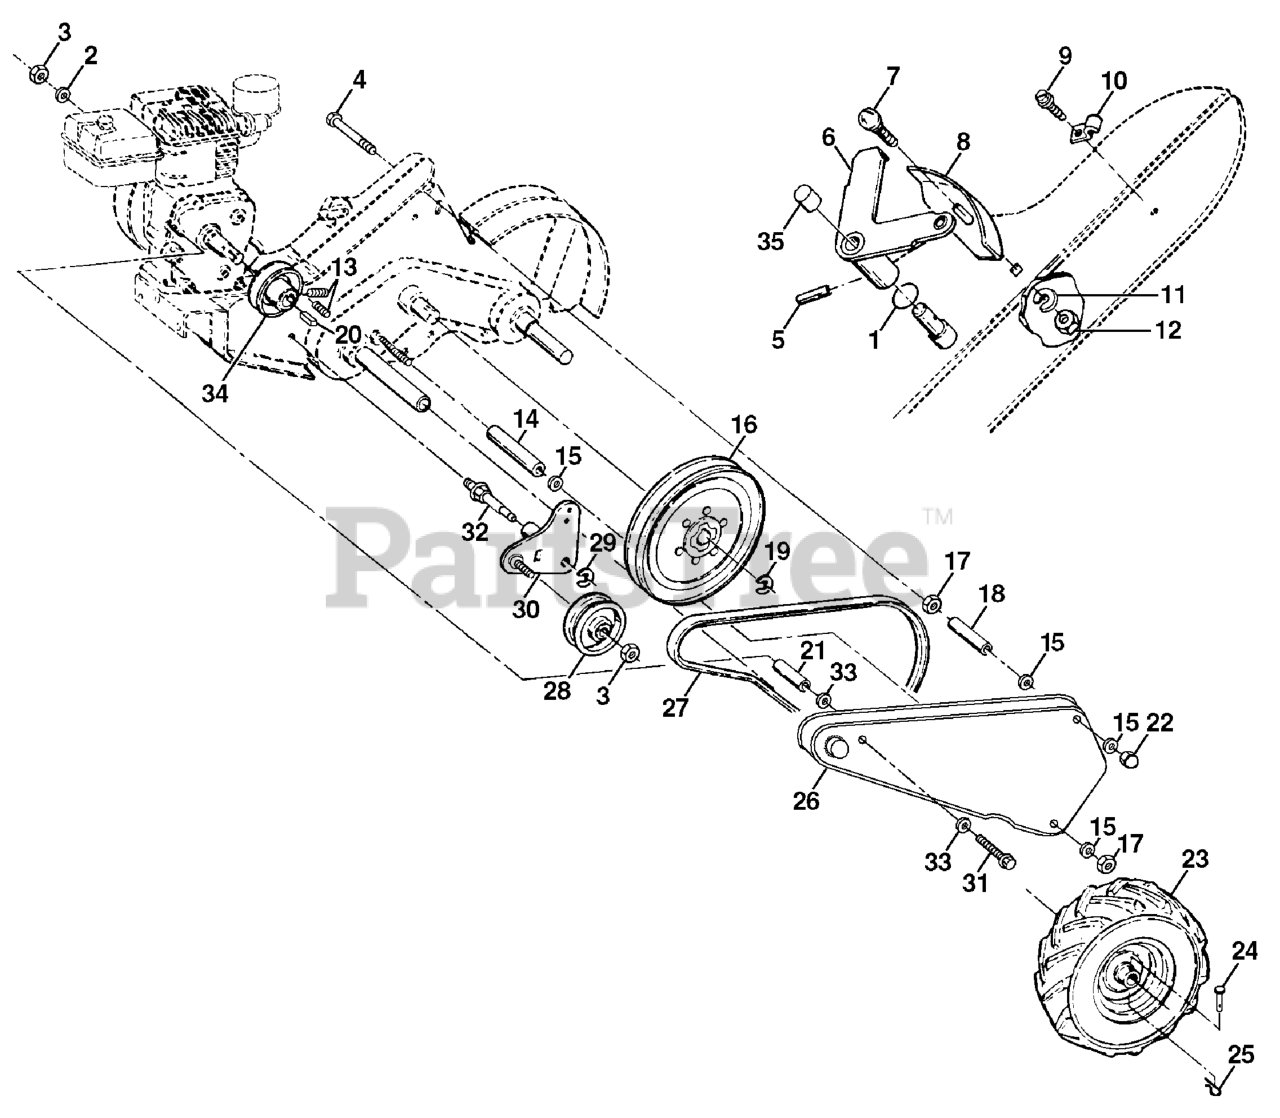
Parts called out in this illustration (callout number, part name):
2	WASHER, LOCK 3/8
3	NUT.HEX.3/8-16UNC
4	BOLT 5/16-18X4 1/2
5	DRIVE PIN
6	LEVER ASM CRT
8	PANEL.INDICATOR.SHIFT.BLACK
9	TAPPING SCREW
10	CONDUIT.CLIP.PLATED
11	LOCKWASHER
12	NUT
14	SPACER, SPLIT
15	WASHER
16	SHEAVE, TRANSMISSION
17	NUT
19	RETAINING RING LT
20	KEY, SQUARE
21	SPACER.SPLIT
23	TIRE.16X4-8.CHEVRON.TILLER
23	RIM
23	VALVE STEM LT
25	SPRING TI
26	BELT GUARD
27	BELT, DRIVE
28	PULLEY, IDLER
30	BRACKET ASSY TI
31	Bolt, Hex Head 1/2-20 x 2-3/4
32	SHAFT, IDLER ARM
33	WASHER
34	SHEAVE, ENGINE
35	CAP.PLUNGER.BLACK
